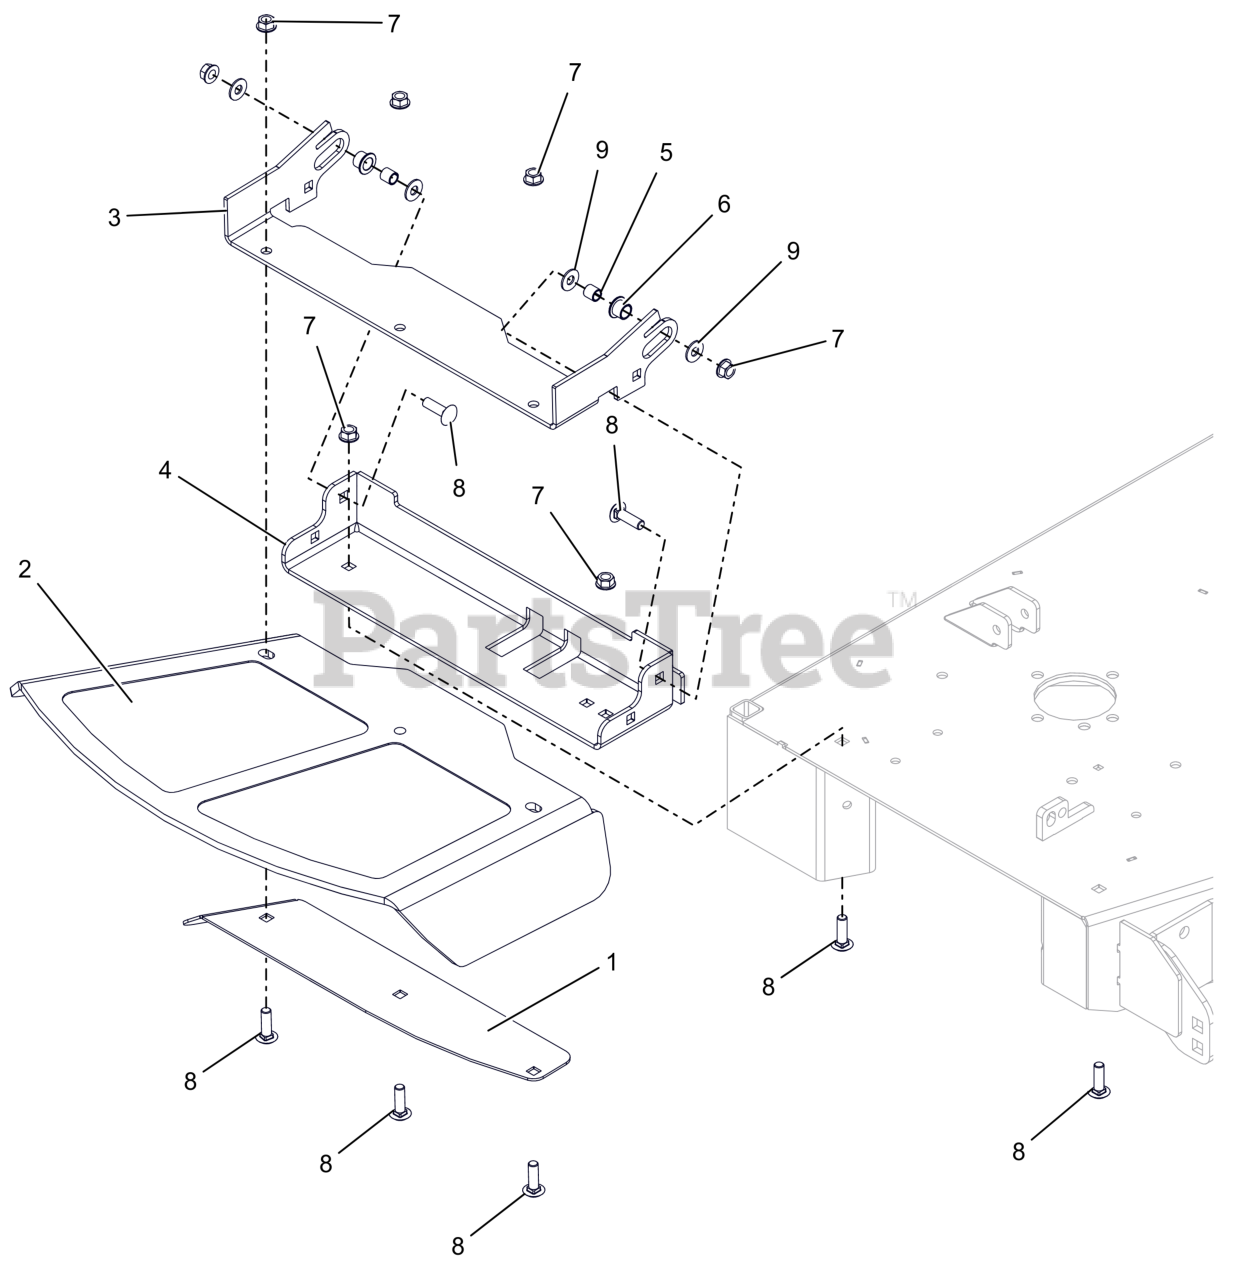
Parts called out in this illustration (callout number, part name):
1	48-60 DISCH CHUTE CLMP PLT-RED
2	CHUTE, FORMED RUBBER DISCHARGE
3	BRKT, CHUTE MOUNT (RED)
4	BASE, DISCHARGE CHUTE MTG BRKT (RED)
5	SPCR, .385X.500X.350
6	BSHG, FLANGED .50X.625X.50X.062
7	NUT-LK-CTR-FLG .375-16 GF ZCC
8	BLT,RHSSN .38-16X1.25 G5 ZCC
9	WSHR, HDND 0.375X0.875X0.064 ZCC
